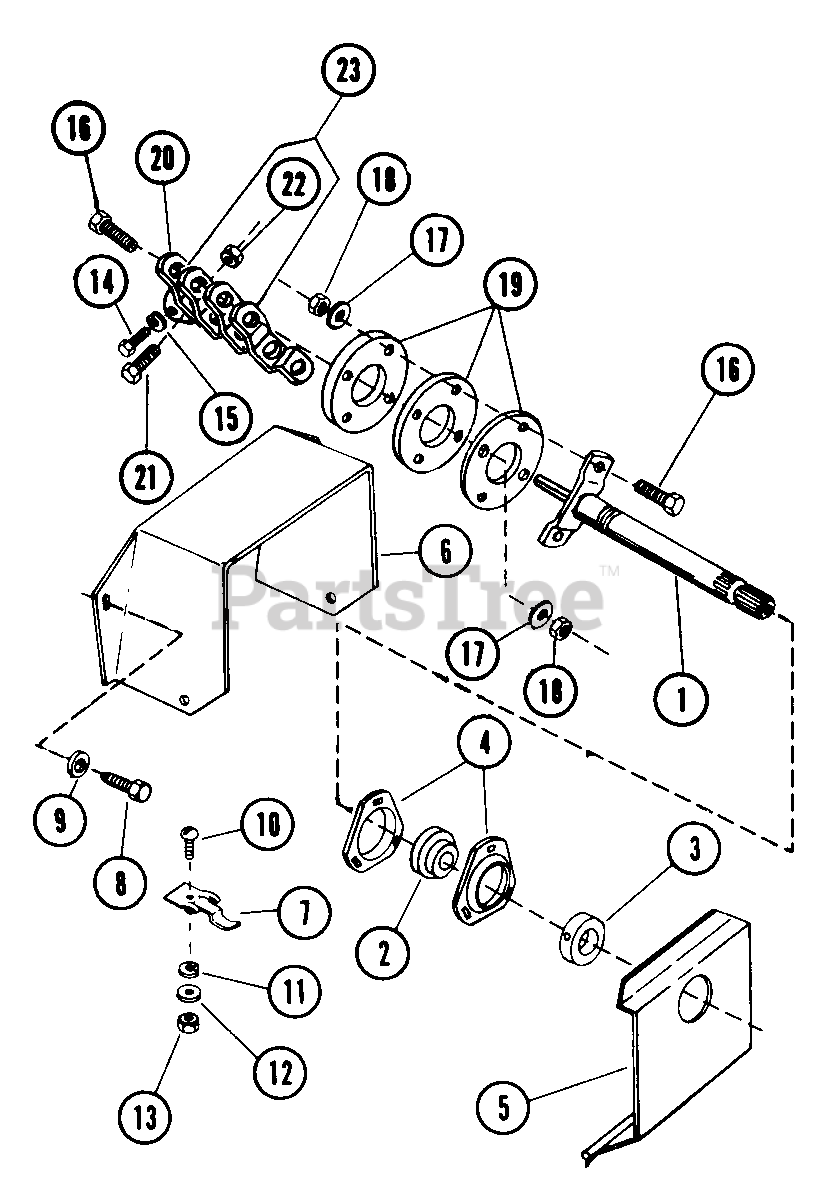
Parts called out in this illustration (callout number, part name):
1	REAR PTO SHAFT ASSEMBLY
2	BRG/W COLLAR 1.0 X 2.047 X.844
3	BEARING COLLAR
4	BEARING FLANGE
5	REAR PTO COVER
6	PTO SHIELD
7	SNAP FASTENER
8	SCR-TAP (NO DRWG)
9	WSHR-FL-STL .38X.875X.083 PL
10	SCR-MCH 10-24X1.00 SLRH PL
11	WSHR-LK-EXT #10 ID X .022
12	WSHR-FL-STL .219X.500X.049 PL
13	NUT-HEX 10-24 PL
14	SCR-SKH .25-20X.75 PL
15	WSHR-LK .250X.077 HVY PL
16	BLT-HEX .31-18X1.25 PL GR5
17	WSHR-FL-STL.344X.688X.065PL
18	NUT-LK .312-18 PL
19	SPACER COUPLING
21	BLT-HEX .25-20X2.00 GR5
22	NUT-LK TOP .250-20 PL
23	ADJUSTING PLATE
